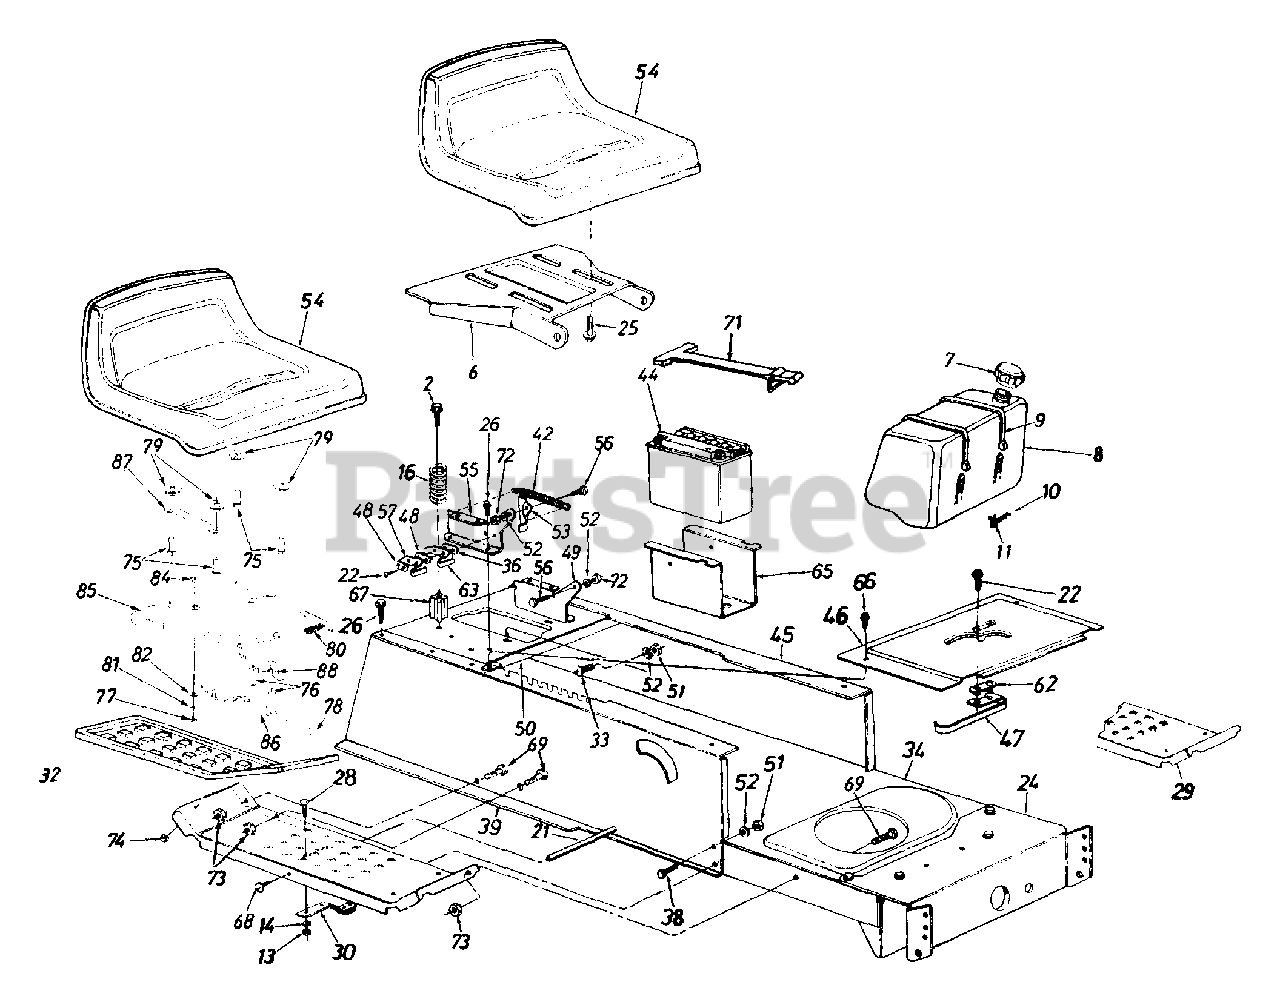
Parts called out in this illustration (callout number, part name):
2	Hex Tap Scr. 5/16-18 x 3.25"
7	Fuel Cap
8	Fuel Tank (1.5 Gal)
9	Tie Strap
10	Fuel Line
11	Hose Clamp
13	Hex Nut 1/4-20 Thd.
14	L-Wash. 1/4" I.D.
16	Compression Spring
21	Running Board Rod
22	Hex AB-Tap Scr. #8 x .50" Lg.
25	Hex Tap Scr. 3/8-16 x .62" Lg.
26	Hex Wash. Hd. AB-Tap Scr. 5/16 x .75"
28	Carriage Bolt 1/4-20 x .62"
32	Rubber Foot Pad - L.H.
36	Insulator Boss Plate
38	Hex Bolt 5/16-18 x .75" Lg.
44	12-V Battery
48	Insulator Plate
52	L-Wash. 5/16" I.D.
53	Seat Lift Brkt.
54	Seat 8-7/8" High
56	Shld. Bolt .437" Dia. x .268"
57	Spring Switch (Seat - Outer)
63	Safety Switch (Seat - Inner)
66	Truss Mach. B-Tap Scr. #10 x .5" Lg.
67	Spring Spacer
68	Truss Mach. Scr. 5/16-18 x .75"
69	Hex Bolt 5/16-18 x .75" Lg.
71	Battery Retainer Strap
72	Hex Nut 5/16-18 Thd.
73	Hex Sems Nut 5/16-18 Thd.
74	Hex Sems Nut 1/4-20 Thd.
75	Shoulder Screw 3/8-16 x .5
76	Hex Wash. B-Tap Scr. #10-16 x .38"
77	Hex Flanged L-Nut 1/4-20 Thd.
78	Seat Adjustable Grip
79	Spacer
80	Compression Spring 1.5" Lg.
81	Spring Wash. .265" I.D. x .56" O.D.
82	Fl-Wash. .344" I.D. x .62" O.D.
84	Shld. Bolt .34" x 14 -20 Thd.
87	Seat Selector
88	Seat Stop
